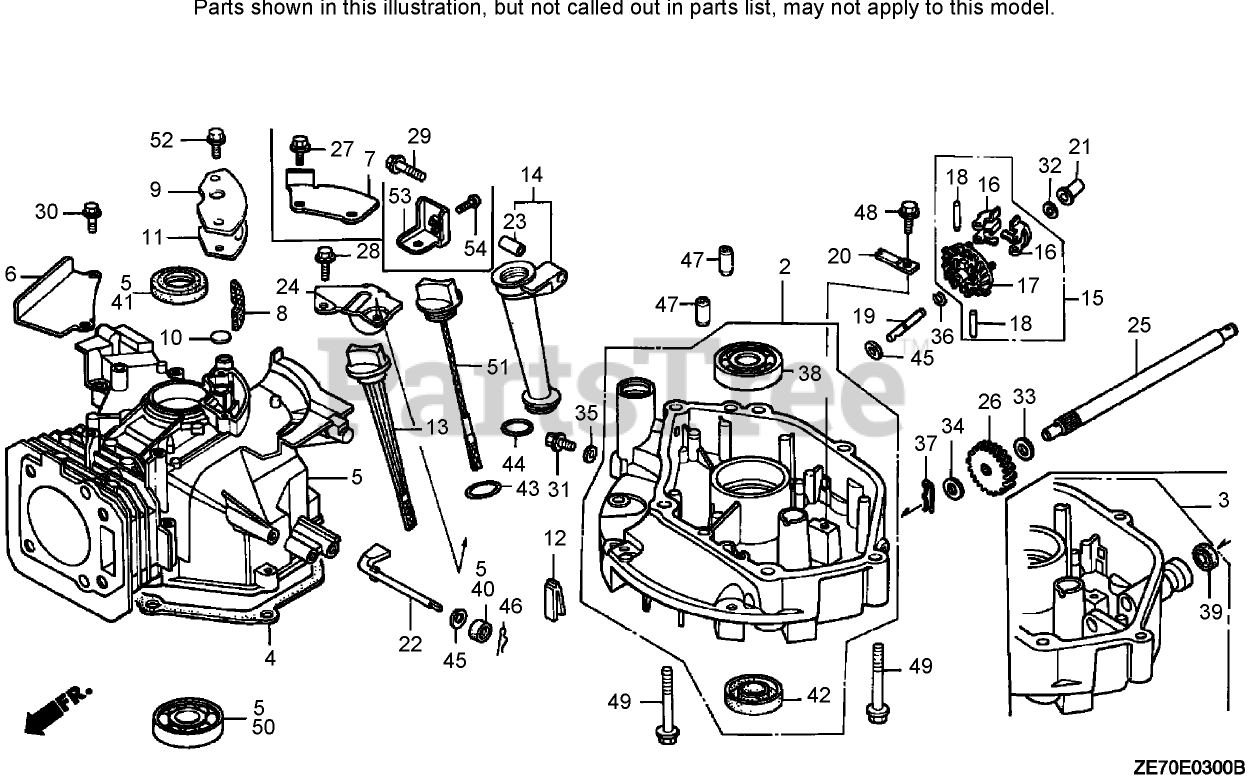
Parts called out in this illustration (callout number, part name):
2	OIL PAN ASM
4	GASKET-PAN, OIL
5	CYLINDER ASM
6	Plate-Guide
7	Plate A-Guide
8	Filter-Breather
9	Cover-Breather
10	VALVE-BREATHER
11	GASKET-COVER, BREATHER
12	RUBBER-RETURN, OIL
13	Dipstick-Oil
14	EXTENSION-FILLER, OIL (106 mm)
15	GOVERNOR ASM
16	Weight-Governor
17	HOLDER-WEIGHT, GOVERNOR
18	PIN-WEIGHT, GOVERNOR
19	SHAFT-HOLDER, GOVERNOR
20	Plate-HOLDER, Governor Shaft
21	SLIDER-GOVERNOR
22	SHAFT-ARM, GOVERNOR
23	Collar-Extension
27	BOLT-FLANGE (6X12) (C T200)
29	Bolt-Flange (6X32)
30	BOLT-FLANGE (6X20) (C T200) (engine serial numbers up to 6702082)
31	Bolt-PLUG, Drain
32	WASHER-THRUST (6MM)
35	WASHER-PLUG, DRAIN (102MM)
36	CLIP-HOLDER, GOVERNOR
40	SEAL-OIL (6X11X4)
41	SEAL-OIL (25X38X7)
41	SEAL-OIL (25X38X7) (ARAI)
42	SEAL-OIL (25.4X40X7)
43	O-Ring (22.5X2.2)
44	O-Ring (26X2.7)
45	WASHER-PLAIN (6MM)
46	PIN-LOCK (8MM)
47	Pin-Dowel (8X14)
48	Bolt-Flange (6X12)
49	BOLT-FLANGE (8X50)
50	BEARING-BALL, RADIAL (6205)
52	BOLT-FLANGE (6X14) (C T200)
